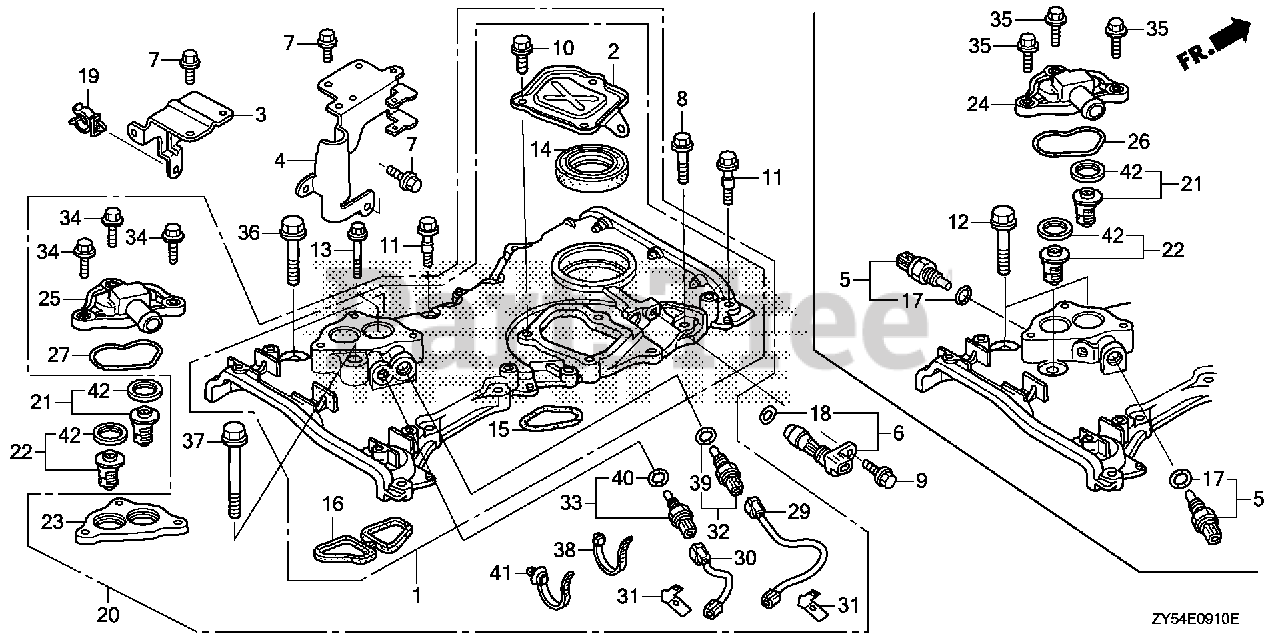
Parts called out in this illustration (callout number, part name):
2	COVER, CHAIN CASE
3	BRACKET B, HARNESS CLIP
4	BRACKET C, HARNESS CLIP
5	SENSOR ASSY., WATER TEMPERATURE
6	SENSOR ASSY., CRANK
7	BOLT, FLANGE (6X14) (CT200)
8	BOLT, FLANGE (6X28)
9	BOLT, FLANGE (6X16)
10	BOLT, FLANGE (6X14)
11	BOLT, SPECIAL (6X31)
12	BOLT, FLANGE (10X43)
13	BOLT, FLANGE (6X38)
14	OIL SEAL (43X58X7) (ARAI)
15	O-RING, CHAIN CASE
16	GASKET, CHAIN CASE
17	O-RING (9.5X1.9)
18	O-RING (15X1.9)
19	CLAMP (18.5MM)
20	CASE KIT, CHAIN
21	THERMOSTAT ASSY.
22	THERMOSTAT ASSY.
23	SPACER KIT, THERMOSTAT COVER
24	COVER, THERMOSTAT
25	COVER, THERMOSTAT
26	GASKET, THERMOSTAT COVER
27	GASKET, THERMOSTAT COVER
29	SUB-WIRE HARNESS ASSY. (A)
30	SUB-WIRE HARNESS ASSY. (B)
31	BRACKET, SUB-HARNESS CLIP
32	SENSOR ASSY., WATER TEMPERATURE
33	SENSOR ASSY., WATER TEMPERATURE
34	BOLT, FLANGE (6X28)
35	BOLT, FLANGE (6X22)
36	BOLT, FLANGE (10X43)
37	BOLT, FLANGE (10X70)
38	BAND, WIRE HARNESS
39	O-RING (9.5X1.5) (HONDA KIKAKI)
40	O-RING (9.5X1.9)
41	CLIP, HARNESS BAND (145MM) (BLACK)
42	RUBBER, RING
